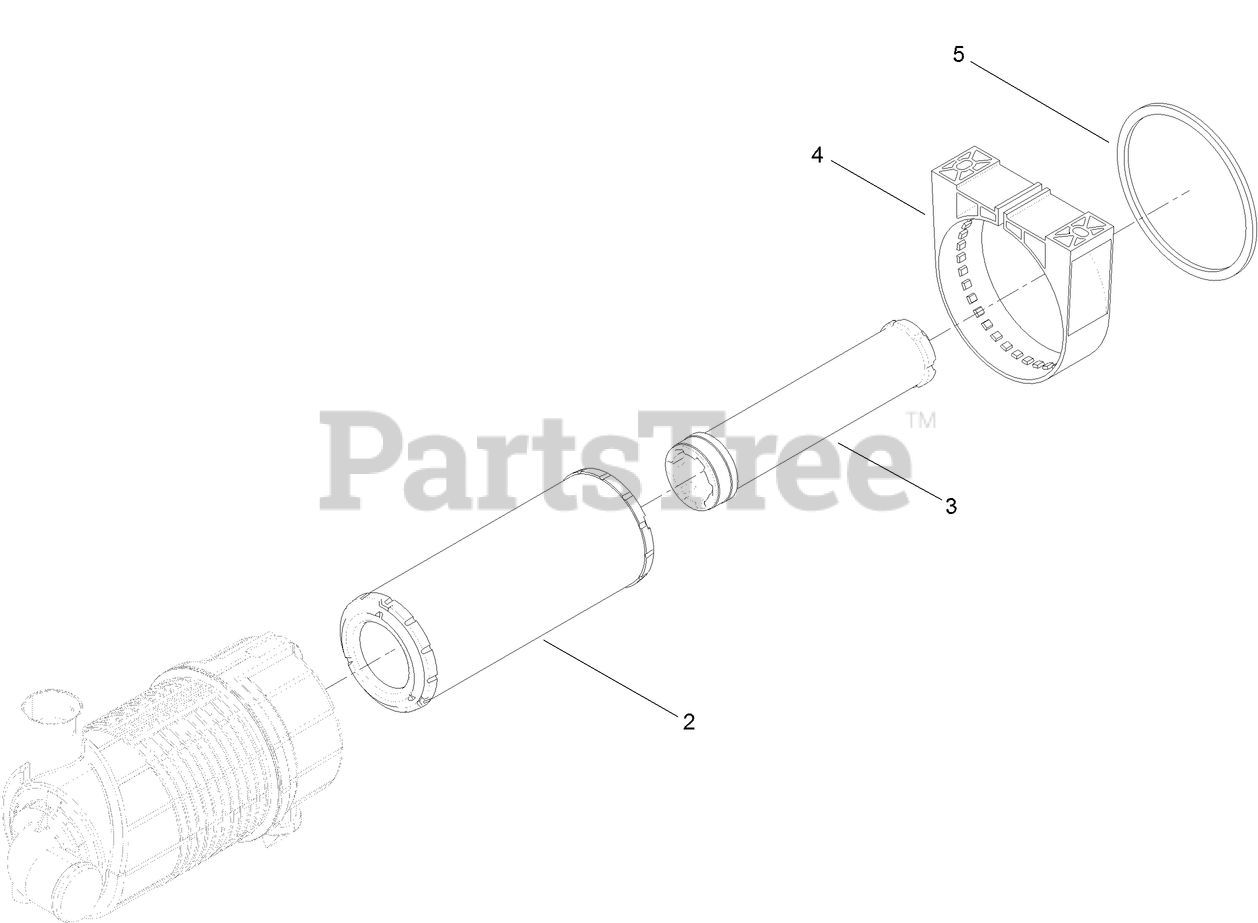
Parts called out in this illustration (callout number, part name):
2	FILTER-AIR
3	ELEMENT-SAFETY, 5 INCH
4	BRACKET-CLEANER, AIR
5	Gasket
